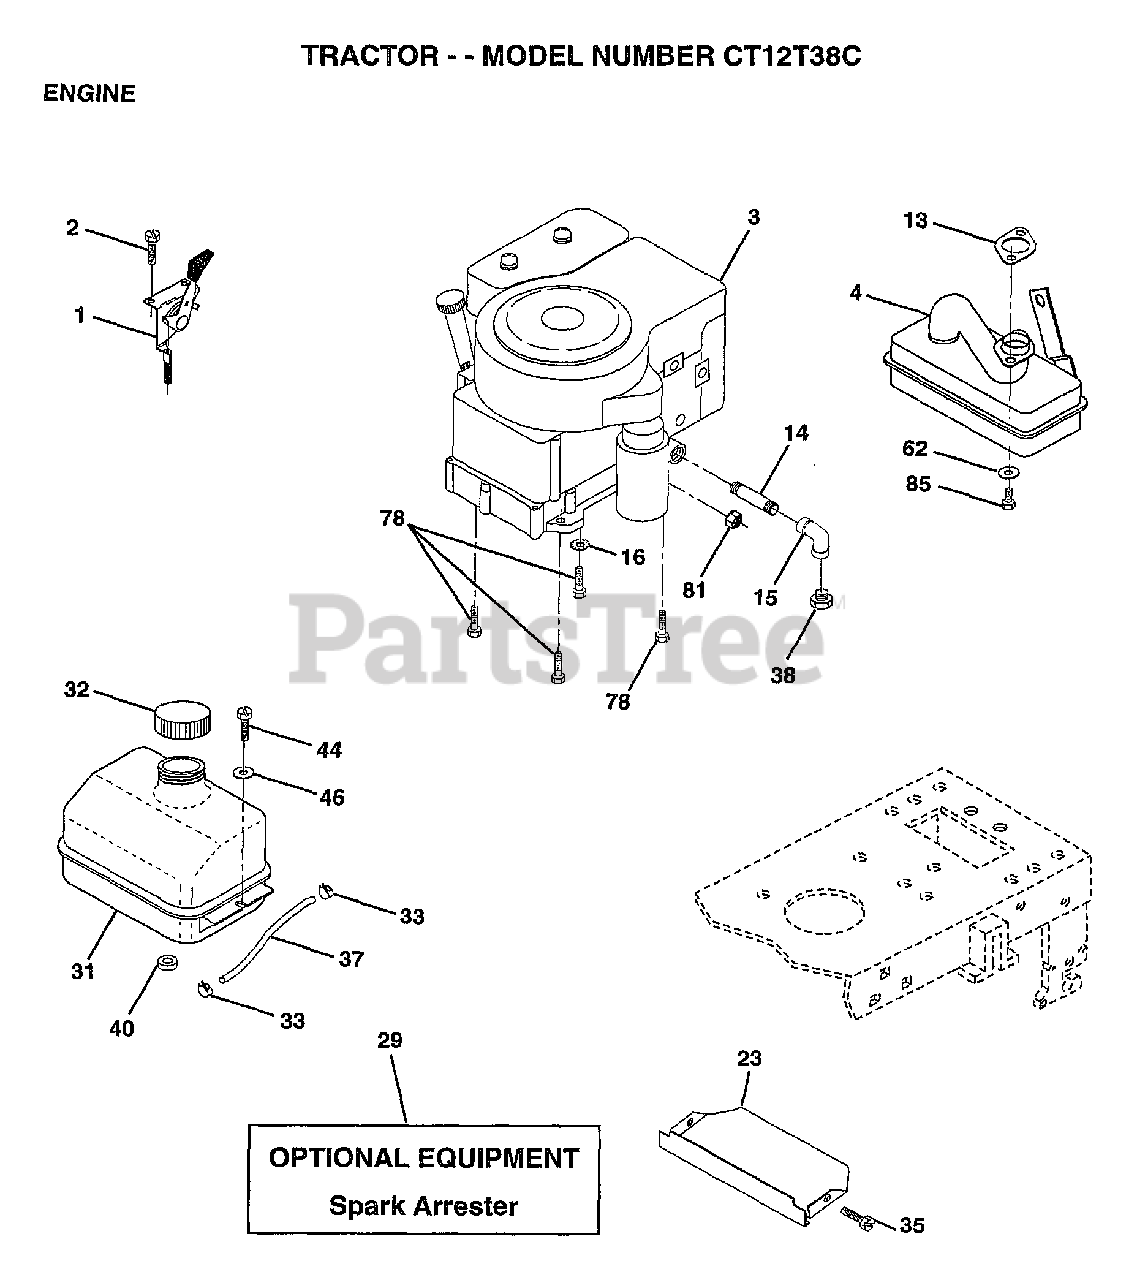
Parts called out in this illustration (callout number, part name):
1	THROTTLE CONTROL
2	SCREW LT
4	MUFFLER TEC. 13HP
13	GASKET ENG 1 313 LD TIN PLATED
14	PIPE NIPPLE LT
15	ELBOW
16	LOCKWASHER
23	SHIELD.BRN/DBR.GD
31	TANK.FUEL.LT.
32	CAP ASM FUEL
33	HOSE CLAMP
35	SCREW
37	LINE FUEL
44	SCREW HEX CRT
46	WASHER
62	LOCKWASHER
78	SCREW
81	NUT
85	SCREW HEX HD CAP
